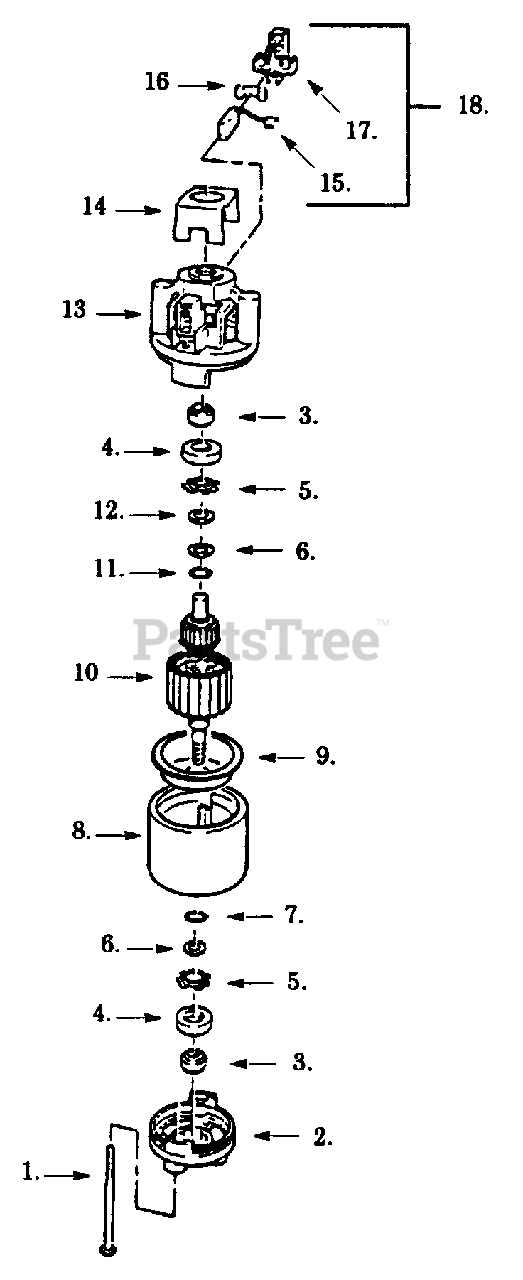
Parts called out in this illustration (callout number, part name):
2	Endbell Output
3	Field Ass'y.
6	Bearing Retainer
8	Retaining Ring
9	Air Deflector
10	Armature
11	Retainer Ring
13	Endbell (Brush)
14	Insulator
17	Brush Holder
18	Brush Kit (Incl. 15,16,17)
